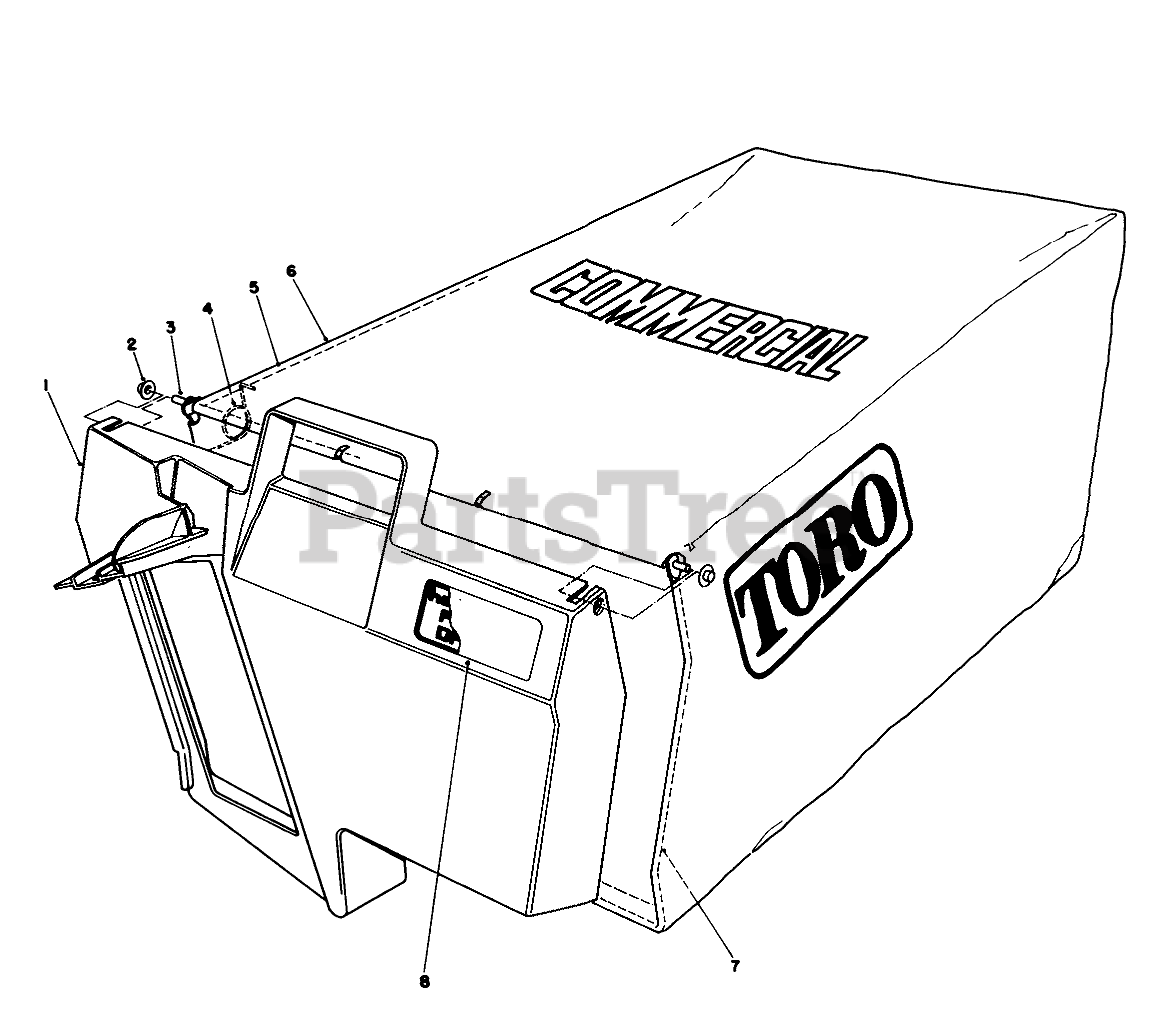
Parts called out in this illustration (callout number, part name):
1	DOOR-BAG, GRASS
2	NUT-PUSH
3	HINGE-DOOR, BAG
4	SPRING
5	FRAME-BAG, UPPER
6	Bag
7	FRAME-BAG
8	BAG DOOR DECAL
